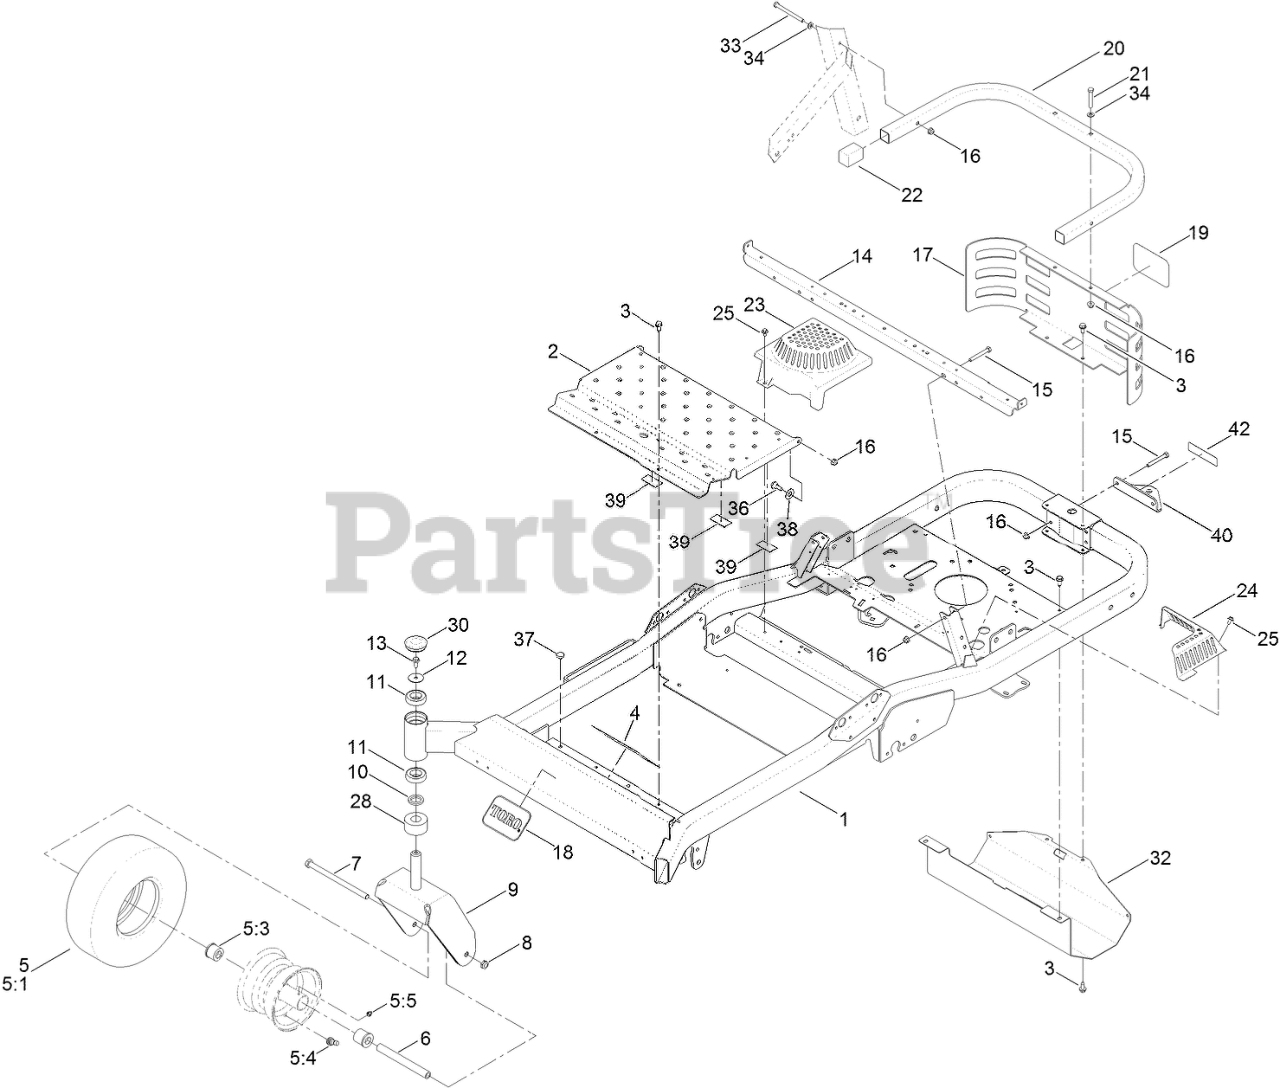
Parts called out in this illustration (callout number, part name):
1	FRAME ASM
2	PAN-FLOOR
3	SCREW-HWHTF
4	DECAL-DANGER
5	TIRE AND WHEEL ASM
5:1	TIRE-13 INCH SMOOTH
5:3	BUSHING-FLANGE
5:4	STEM-VALVE
5:5	FITTING-GREASE
6	SPANNER
7	SCREW-HH
8	NUT-LOCK, NI
9	FORK-CASTER
10	WASHER-THRUST
11	BEARING-BALL
12	WASHER-FLAT
13	SCREW-HHF
14	SUPPORT-SEAT
15	SCREW-HH
16	NUT-HF, NI
17	GUARD-REAR
18	DECAL
20	TUBE-GUARD
21	SCREW-HH
23	COVER-FAN, RH
24	COVER-FAN, LH
25	SCREW-HHFTF
28	SPACER-CASTER
30	CAP-GREASE
32	SHIELD-HEAT
33	SCREW-HH
34	WASHER-PLAIN
36	SCREW-SHOULDER
37	BUMPER
38	WASHER-TEFLON
39	PAD-RUBBER
40	BRACKET-HITCH
